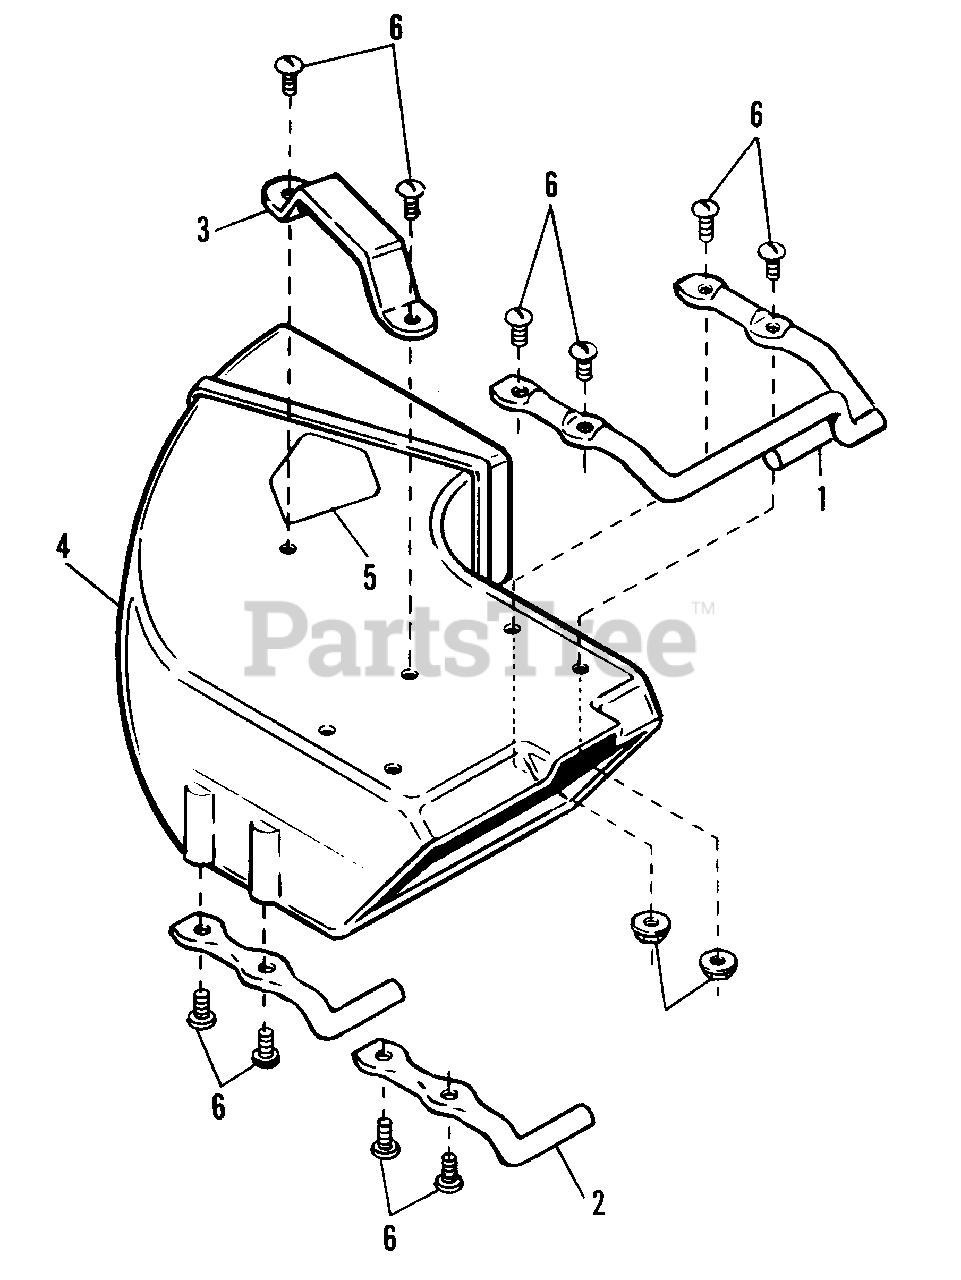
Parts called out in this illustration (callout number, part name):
1	FRAME, Upper Chute
2	FRAME, Lower Chute
3	HANDLE, Chute
4	CHUTE, Rear Discharge
5	DECAL, Danger
6	SCREW, Slotted Truss Hd., 1/4-20 x 5/8
7	LOCKNUT, 1/4-20 Flanged Whiz
